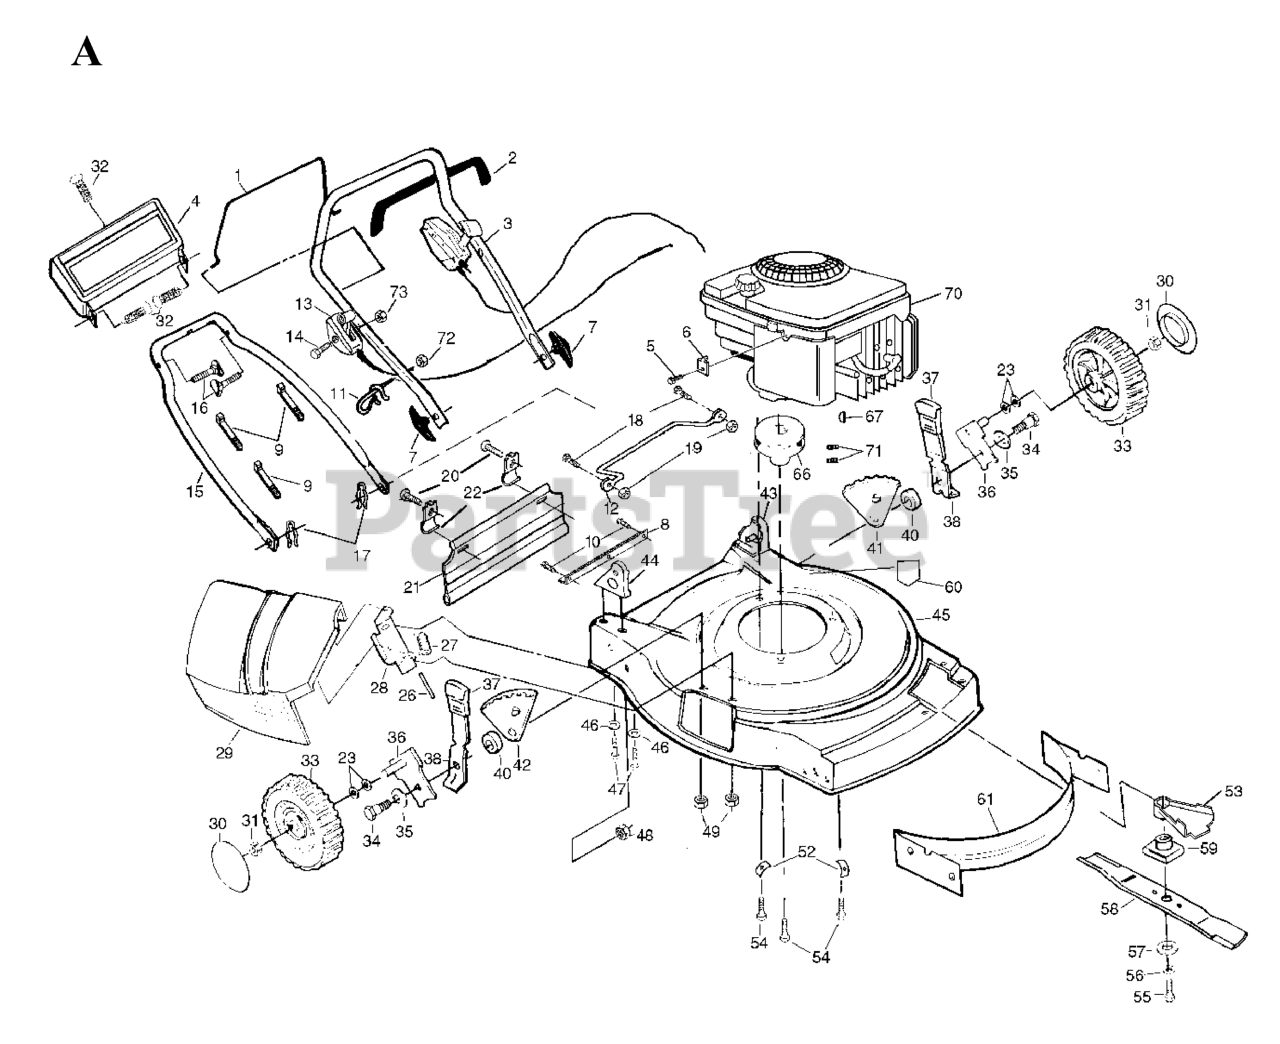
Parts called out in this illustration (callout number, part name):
1	CONTROL BAR
2	HANDLE GRIP
3	UPPER HANDLE
4	TRIM PLATE
5	SCREW.HEX.HEAD.WASHER.10-16
6	WASHER
7	HANDLE KNOB
9	CLIP CABLE SNAP
11	ROPE GUIDE
13	THROTTLE CONTROL
14	SCREW 1/4-20X1.75
15	HANDLE, LOWER
16	HANDLE BOLT
17	HAIRPIN COTTER
20	TAPPING SCREW
21	REAR SKIRT
22	BRACKET DEFL PM
23	WAVE WASHER
24	REPL BY 817 02 10-08
26	ROD.HINGE.COMBI-C
28	BRACKET PM
29	DISCHARGE GUARD
31	HEX FLANGE LOCKNT
33	WHEEL.8X2.PR.LP.RAD.GREY
34	BOLT
35	WASHER.BELLEVILLE (3 2 LB)
36	AXLE ARM
37	SELECTOR KNOB
40	RP SPACER HT ADJ
41	WHL ADJ BRKT RF/LR
42	WHL ADJ BRKT LF/RR
43	HDLE BRKT ASSY LH
44	HDLE BRKT ASSY RH
47	SCREW.5/16-18X3/4
48	LOCKNUT PM
49	NUT
52	WASHER.ENGINE.BZP
53	DEBRIS SHIELD
54	BOLT 3/8-16X1-1/8
55	SCREW, HEX HD 3/8-24 X 1-3/8
56	LOCKWASHER
57	WASHER,HARDEN
59	BLADE ADAPTOR
60	DECAL MOWER CUT/FINGER
66	ENGINE.PULLEY.FWG
67	HI PRO KEY PM WSL
72	NUT
73	NUT
